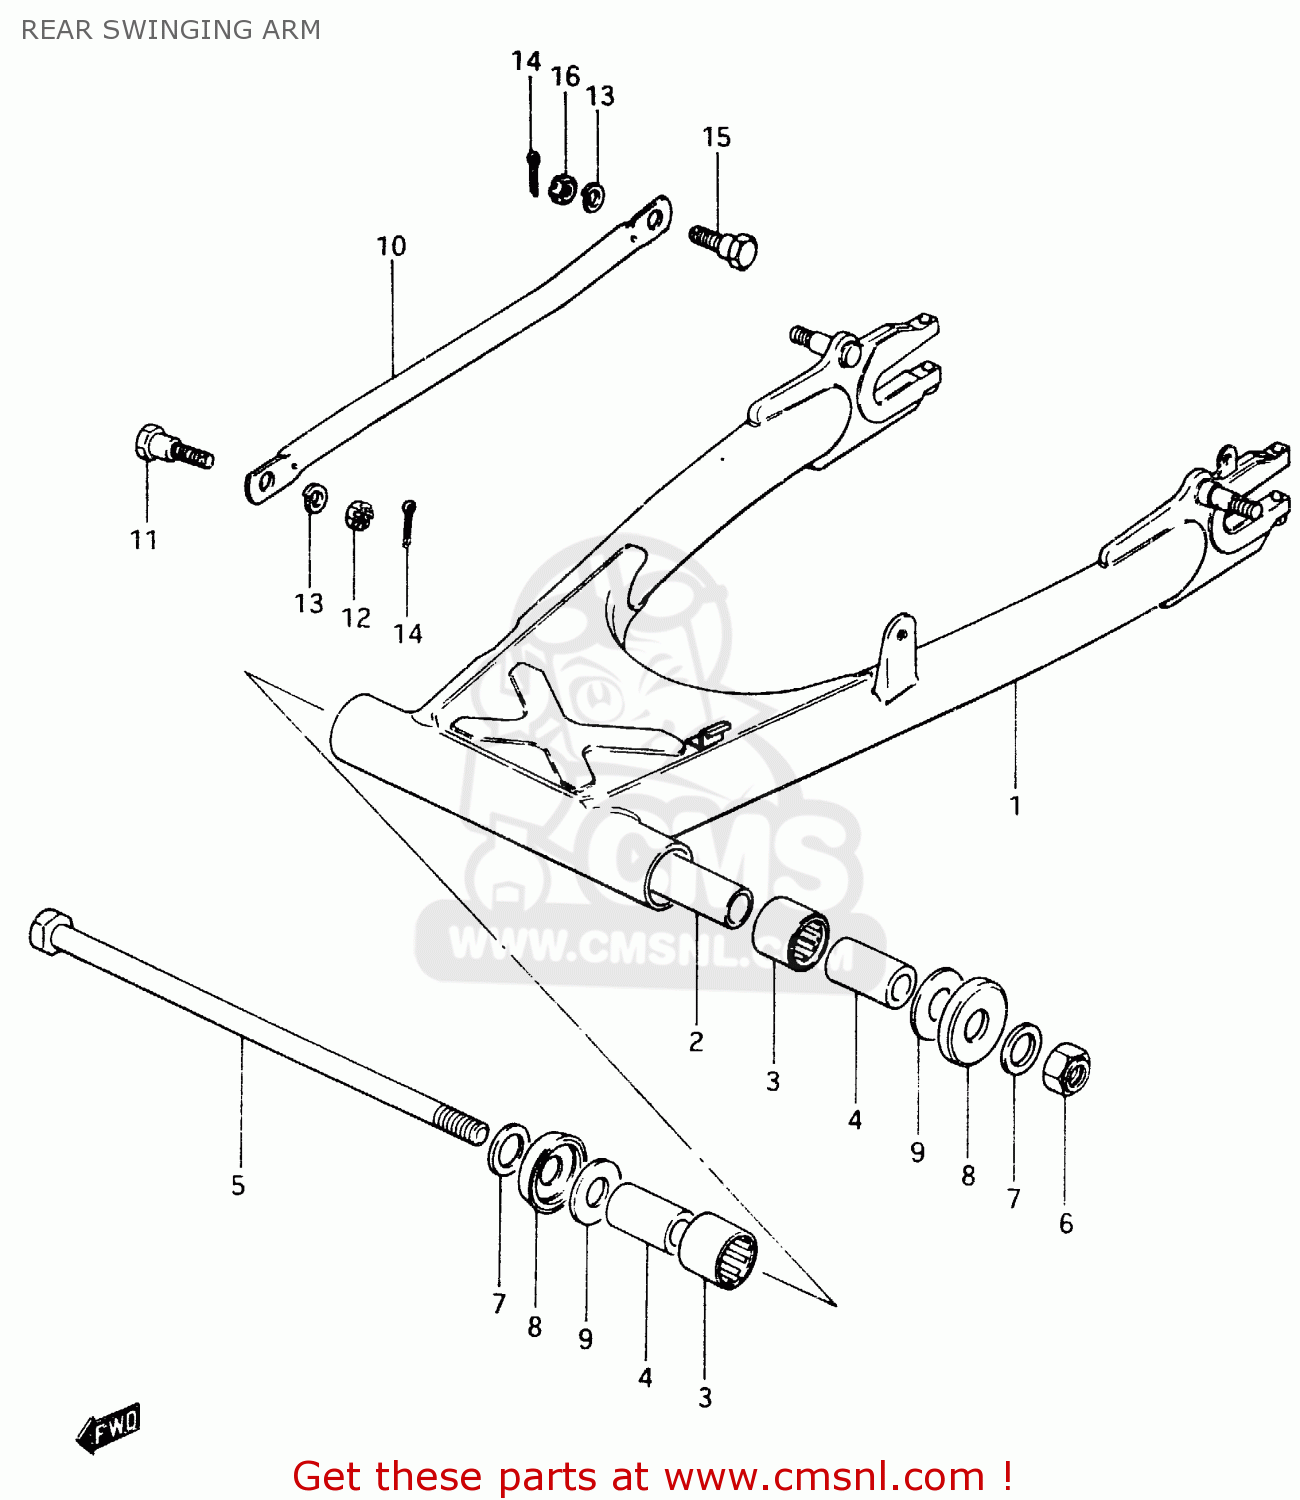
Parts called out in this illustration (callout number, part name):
1	REAR SWINGING ARM
2	SPACER,RR SWGARM PIVOT CTR
3	BEARING(22X29X30)
4	SPACER,RR SWGARM PIVOT
5	SHAFT,REAR SWING ARM
6	NUT 14MM
7	WASHER
8	CVR,RR SWGARM DUST SEAL(OD:40)
9	WASHER(14.2X34X1)
10	TORQUE LINK,REAR
11	BOLT(10X24.5)
12	NUT
13	LOCK WASHER
14	PIN 20X20
15	BOLT(10X31)
16	NUT
